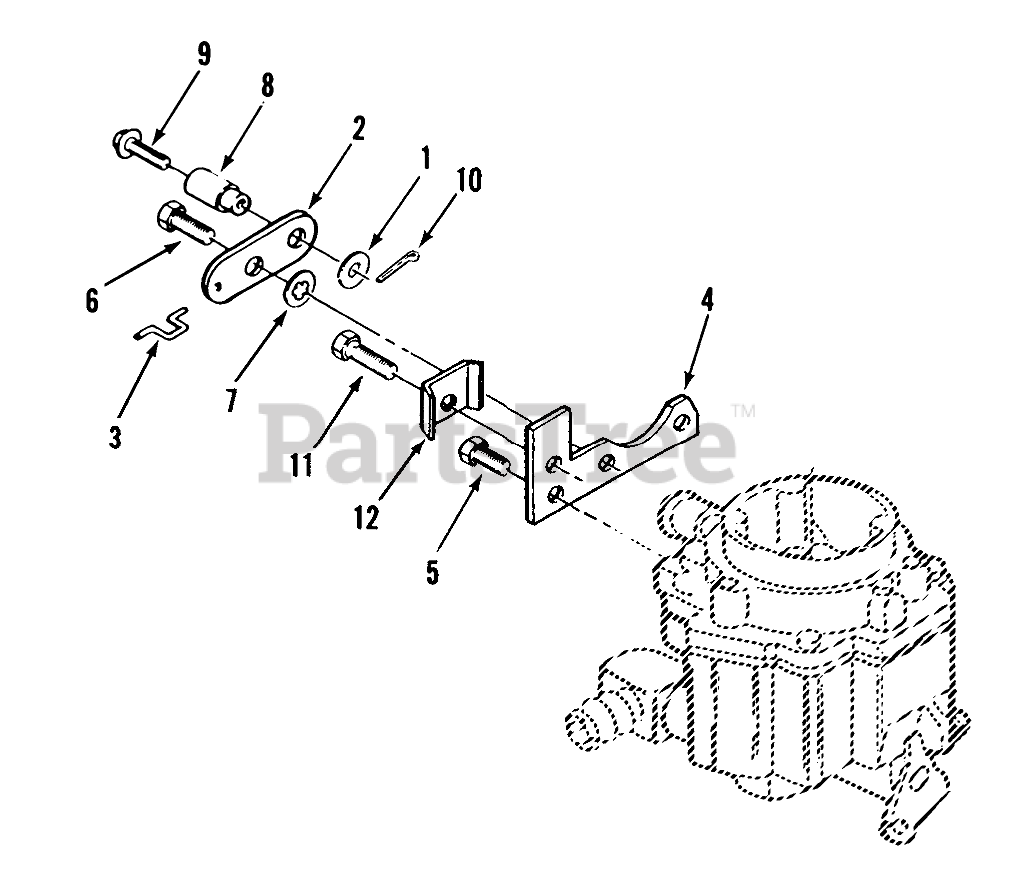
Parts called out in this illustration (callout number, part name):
1	Washer
2	Lever
3	Link
4	Bracket
5	Bolt
6	Bolt
7	Lockwasher
8	Swivel
9	Bolt
10	Cotler Pin
11	Bolt
12	Clip
